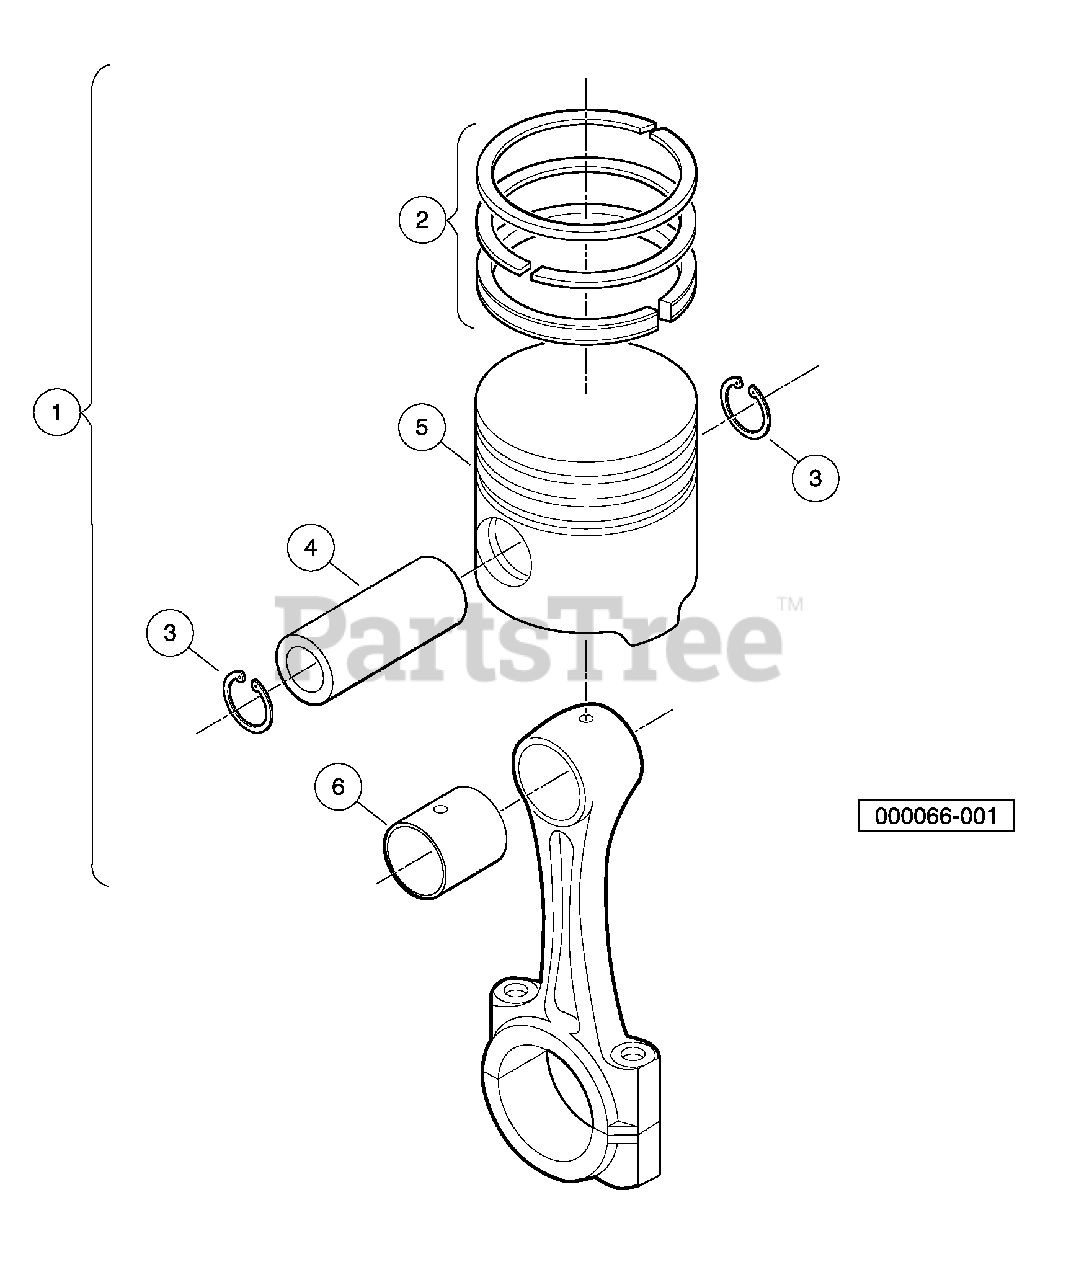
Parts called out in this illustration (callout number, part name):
1	Kit, Piston Rebuild, D722
2	Assy Piston Ring, D722 Std
3	Circlip, Piston Pin
4	Pin, Piston
5	Piston, D722, Std
6	Bushing, Piston Pin, D722
